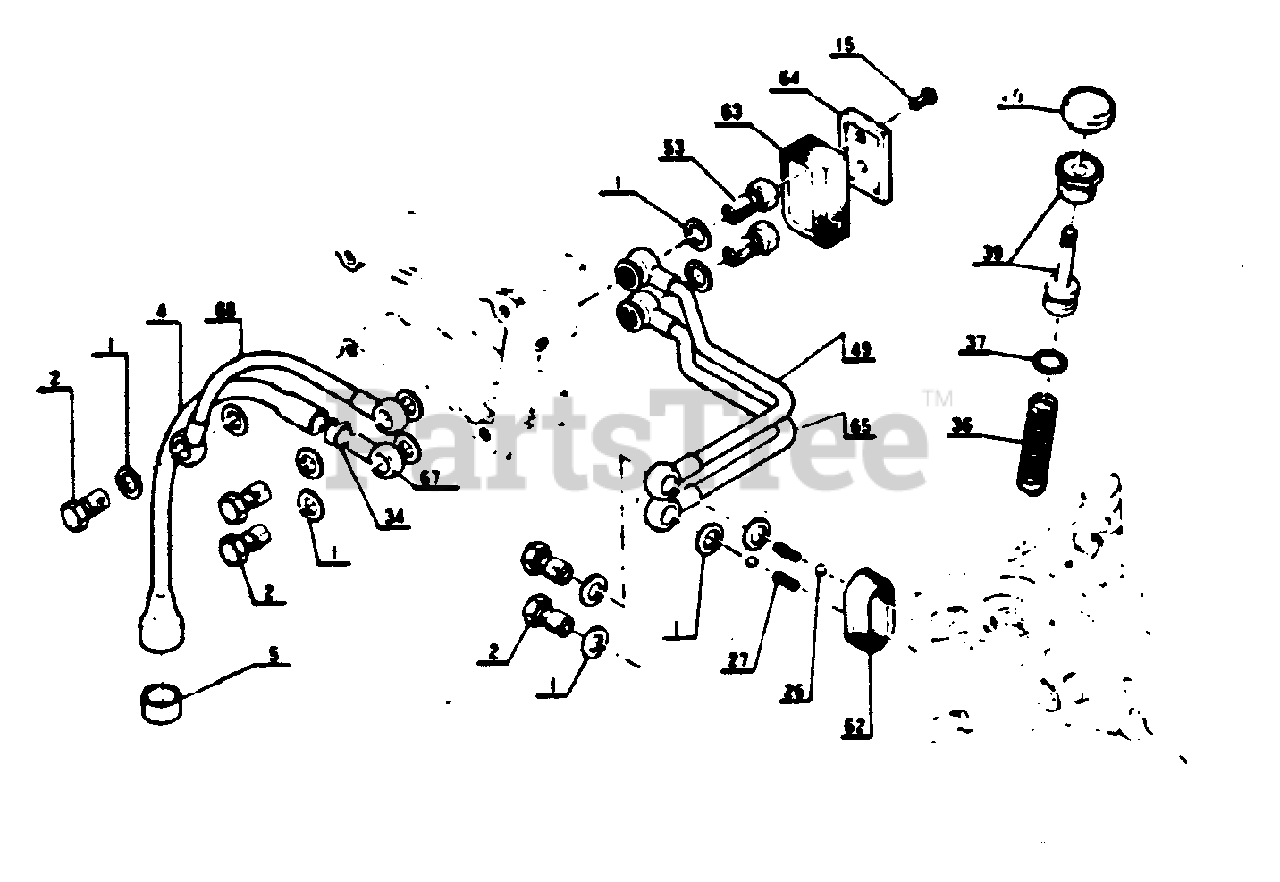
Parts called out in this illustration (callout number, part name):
1	GASKET
4	PIPE, OIL - INNER
5	FILTER, OIL
15	SCREW - 3X6
26	VALVE, BALL
27	SPRING, VALVE
34	CLIP
36	SPRING, OIL PUMP
37	O-RING
39	PISTON, OIL PUMP
40	PUSH BUTTON
49	PIPE - OIL
53	BOLT
63	SEAL, DUST
64	SEAL, DUST
65	PIPE - OIL
67	CONNECTOR
68	PIPE - OIL
